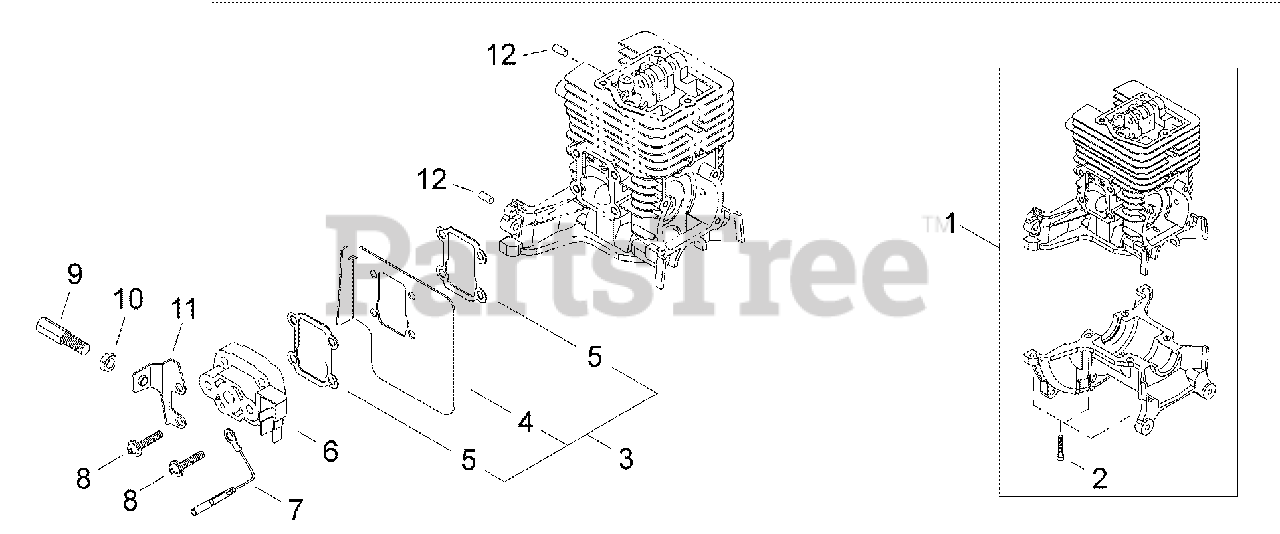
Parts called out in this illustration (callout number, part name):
1	CYLINDER & CRANKCASE ASSY
2	BOLT 5×16
3	SHIELD ASSY, INTAKE HEAT
4	HEAT SHIELD, INTAKE
5	GASKET, EXHAUST
6	INSULATOR WITH REED VALVE
7	LEAD - GROUND L= 110 MM
8	SCREW M5×22
9	ADJUSTER, THROTTLE CABLE
10	NUT, ADJUSTER LOCK M6
11	BRACKET, THROTTLE CABLE
12	PIN, LOCATING Ø4×8
